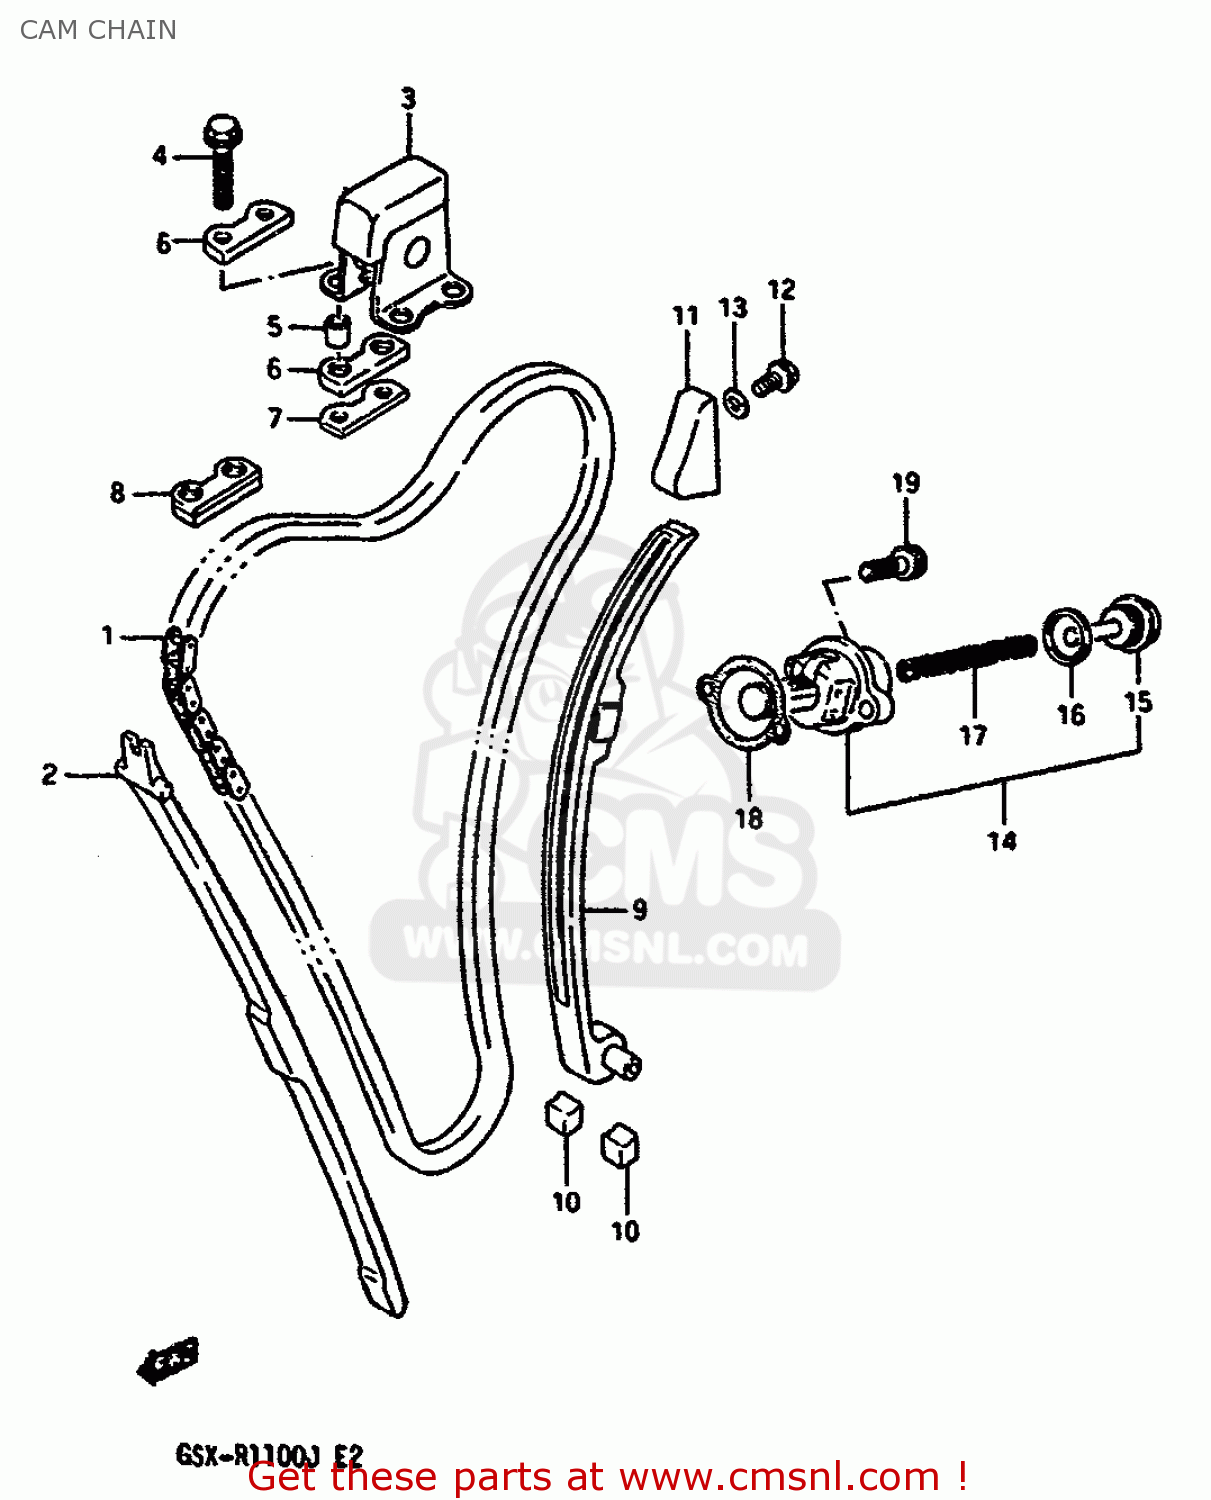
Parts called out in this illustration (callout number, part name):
1	CHAIN,CAMSHAFT DRIVE
2	GUIDE,CAM CHAIN NO.1
3	IDLER,CAM CHAIN
4	BOLT
5	SPACER (6,8X10X9.4)
6	GUIDE,CAM CHAIN
7	PLATE,CAM CHAIN IDLER
8	GUIDE,CAM CHAIN
9	TENSIONER,CAM CHAIN
10	CUSHION,CAM CHAIN TENSIONER
11	GUIDE,CAM CHAIN NO.2
12	BOLT
13	GASKET(5.8X13X1.2) (NAS)
14	ADJUSTER ASSEMBLY,TENSIONER
15	PLUG
16	GASKET (NAS)
17	SPRING
18	GASKET,TENSIONER ADJUSTER (NAS)
19	BOLT
